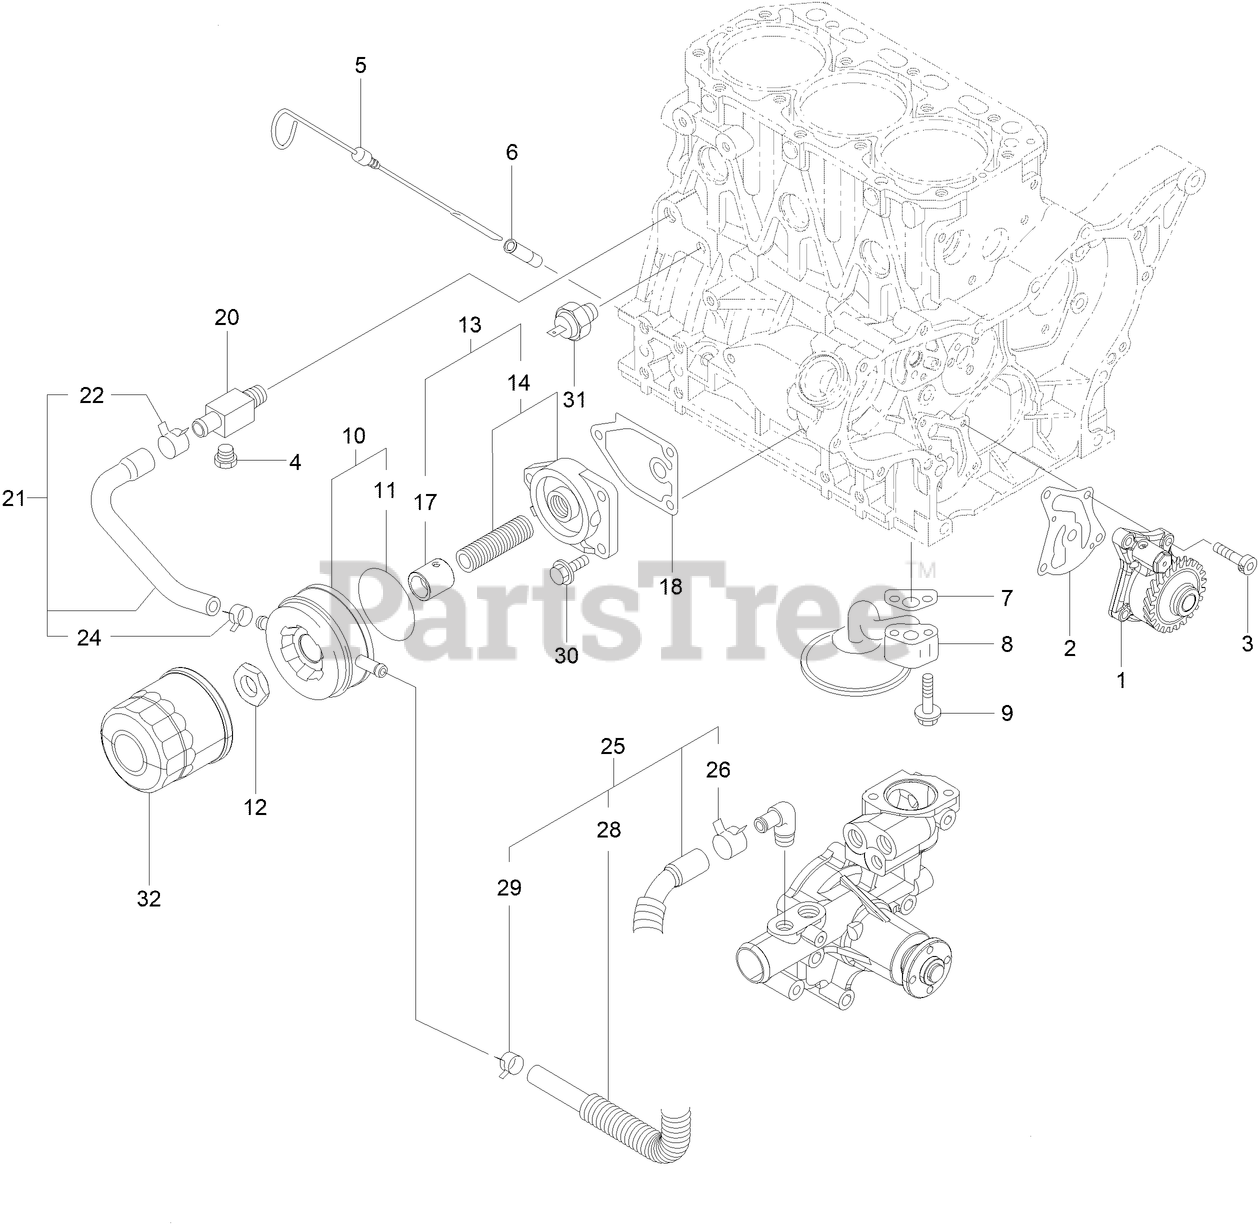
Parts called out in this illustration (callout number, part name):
1	OIL PUMP ASM
2	GASKET
4	PLUG-DRAIN
5	DIPSTICK
6	GUIDE-DIPSTICK
7	GASKET
8	PIPE ASM
10	COOLER ASM-OIL
11	PACKING-OIL COOLER
13	BRACKET ASM-LO FILT
14	BRACKET ASM
17	COLLAR-OIL COOLER
18	GASKET
21	PIPE ASM
24	CLAMP-HOSE
25	PIPE ASM
29	CLAMP-HOSE
31	SWITCH-OIL
32	FILTER-ENGINE
